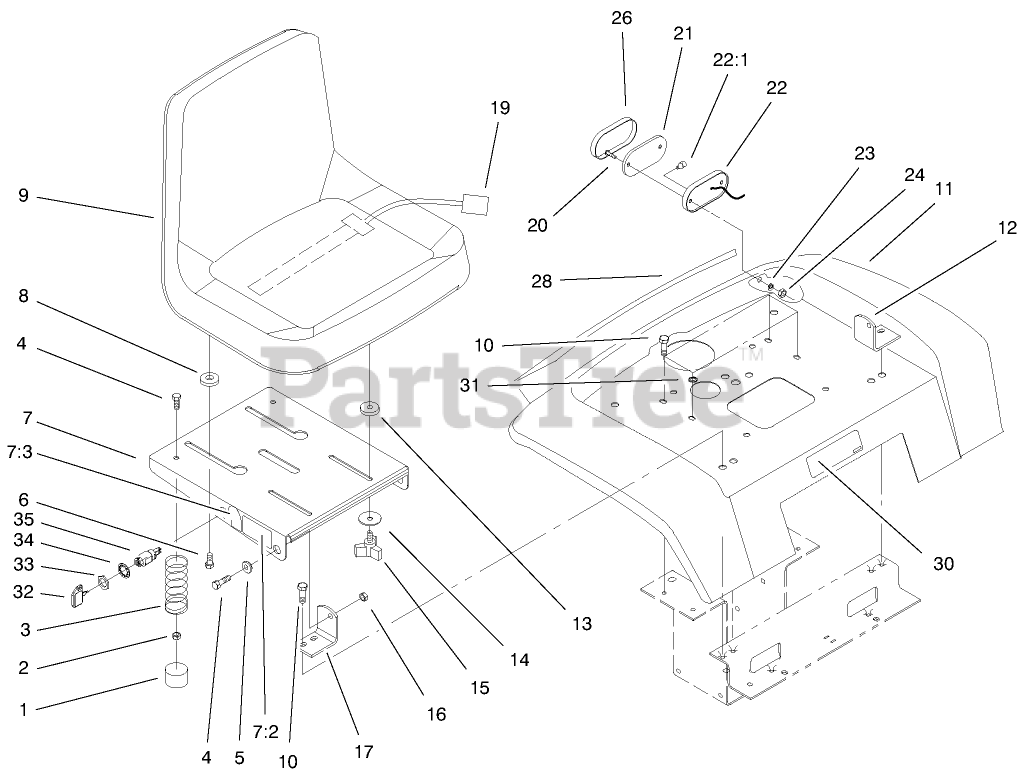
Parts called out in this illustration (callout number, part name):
1	CAP-PROTECTOR
2	NUT-LOCK, NI
3	SPRING-COMPRESSION
4	SCREW-HH
5	BUSHING
6	BOLT-SHOULDER
7	SUPPORT-SEAT
7:2	DECAL-DANGER
7:3	DECAL-SWITCH, NMIR
8	SPACER-NYLON
12	BRACKET-PIVOT, LH
13	SPACER-NYLON
14	WASHER
16	NUT-LOCK, NI
17	BRACKET-PIVOT, RH
19	SWITCH-SEAT
20	SCREW-PPH
22:1	LIGHT BULB
23	WASHER-LOCK, INT
24	NUT-LOCK, NI
26	LENS-TAIL LIGHT
30	DECAL - USA
31	WASHER-LOCK
32	KEY-IGNITION
33	NUT-HH
34	WASHER-LOCK
35	STARTER SWITCH ASM
